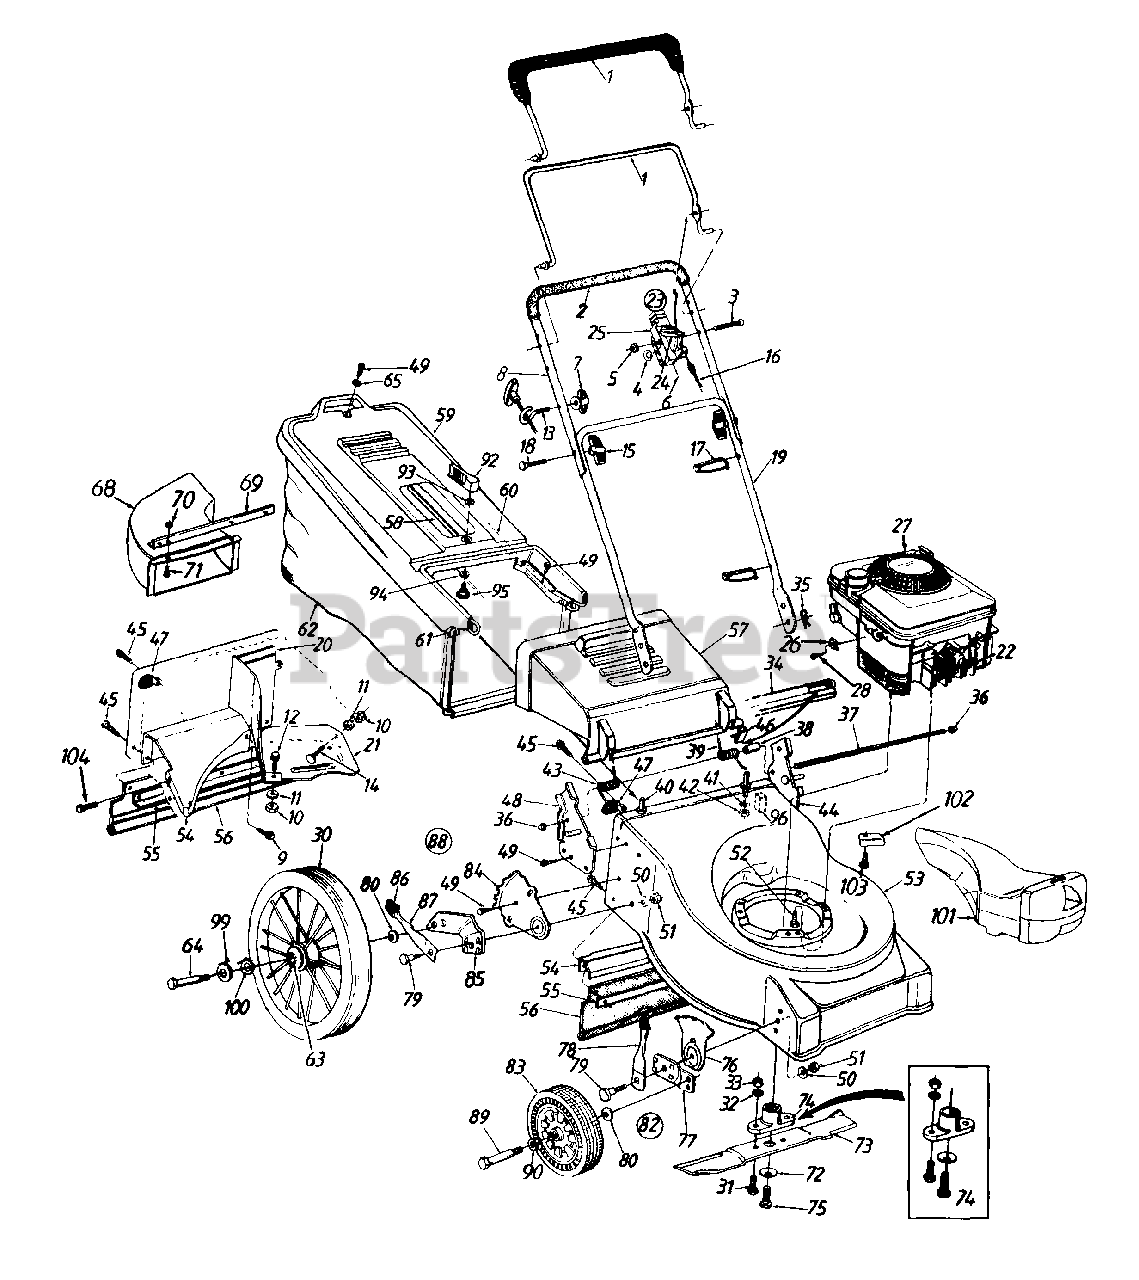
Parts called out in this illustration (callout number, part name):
2	Foam Grip
3	Oval C-Sunk Scr.
4	Spr. Wash. .66" I.D.
5	Hex L-Nut 1/4-20 Thd.
6	Throttle Cable - 55"
7	Handle Knob 1/4-20 Thd.
10	Hex Nut 1/4-20 Thd.
11	L-Wash. 1/4" I.D.
12	Hex Bolt 1/4-20 x .85" Lg.
13	Rope Guide
14	Carr. Bolt 1/4-20 x .5" Lg.
15	Hand Knob
16	Control Cable - 40.5"
17	Cable Tie
18	Curved Hd. Bolt 5/16-18 x 2" Lg.
22	Spark Plug Boot
23	Throttle Box Comp.
24	Throttle Lever
25	Throttle Body
26	Cable Clamp
27	Engine
28	Hex Self-Tap Scr. #10-32 x .62" Lg.
30	Wheel Ass'y. Comp. - Steel Rim
31	Hex Bolt 3/8-24 x 1"
32	L-Wash. 3/8" I.D.
33	Hex Nut 3/8-24 Thd.
34	Seal - Extrusion
35	Int. Cotter Pin 5/16" Dia.
36	Cap Speed Nut
37	Hinge Pin 17.75" Lg.
38	Spacer .255" I.D.
39	Torsion Spring - L.H.
40	Shld. Pin 3/8-24 x 1.43" Lg.
41	L-Wash. 3/8" I.D.
42	Hex Jam Nut 3/8-24 Thd.
43	Torsion Spring - R.H.
46	Deflector Plug
47	Corner Plug
48	Handle Brkt. Ass'y. - R.H.
49	Hex L-Wash. B-Tap Scr. 1/4 x .62" Lg.
50	Bell-Wash. .39" I.D.
51	Hex Nut 3/8-16 Thd.
52	Hex L-Wash. Hd. Scr. 3/8-16 x 1" Lg.
57	Rear Chute Deflector
58	Hardtop Handle
59	Hardtop Bag Cover
60	Rear Catcher Frame
62	Grass Bag
63	Bearing (2 Per Wheel)
64	Shld. Bolt .5 Dia. x 2.62"
65	Fl-Wash. .281" I.D.
68	Chute Deflector
70	Hex L-Nut 1/4-20 Thd.
71	Mach. Scr. 1/4-20 x .5" Lg.
72	Bell-Wash. .39" I.D.
73	21" Blade
74	Blade Adapter Kit
75	Hex Bolt 3/8-24 x 1.5"
76	Height Adj. Plate
77	Pivot Bar
78	Spring Lever Ass'y. w/Knob
79	Shld. Bolt .50" Dia. x .357"
80	Bell-Wash. .38" I.D. x .88" O.D.
82	Height Adj. Ass'y. Comp. - R.H.
83	Front Wheel Ass'y. Comp.
84	Index Plate
85	Pivot Bar - R.H.
86	Spring Lever Knob
87	Spring Lever
88	Rear Height Adj. Ass'y. Comp. - R.H.
89	Front Axle Bolt
90	Wave Wash. .51" I.D. x .78" O.D. (Used w/Ball Brg.)
92	Grass Catcher Locking Knob
93	Internal L-Wash. 1/4" I.D.
94	Wave Washer 3/8" I.D.
95	Shld. Bolt .342" Dia. x .268"
99	Fl-Wash. .51" I.D. x 1.373"
100	Spr. Wash. .5" I.D. x 1" O.D.
101	Mulching Plug
102	Stop Bracket
103	Hex Tap Scr. 3/8-16 x .75" Lg.
104	Hex B-Tap Scr. 1/4 x .38" Lg.
